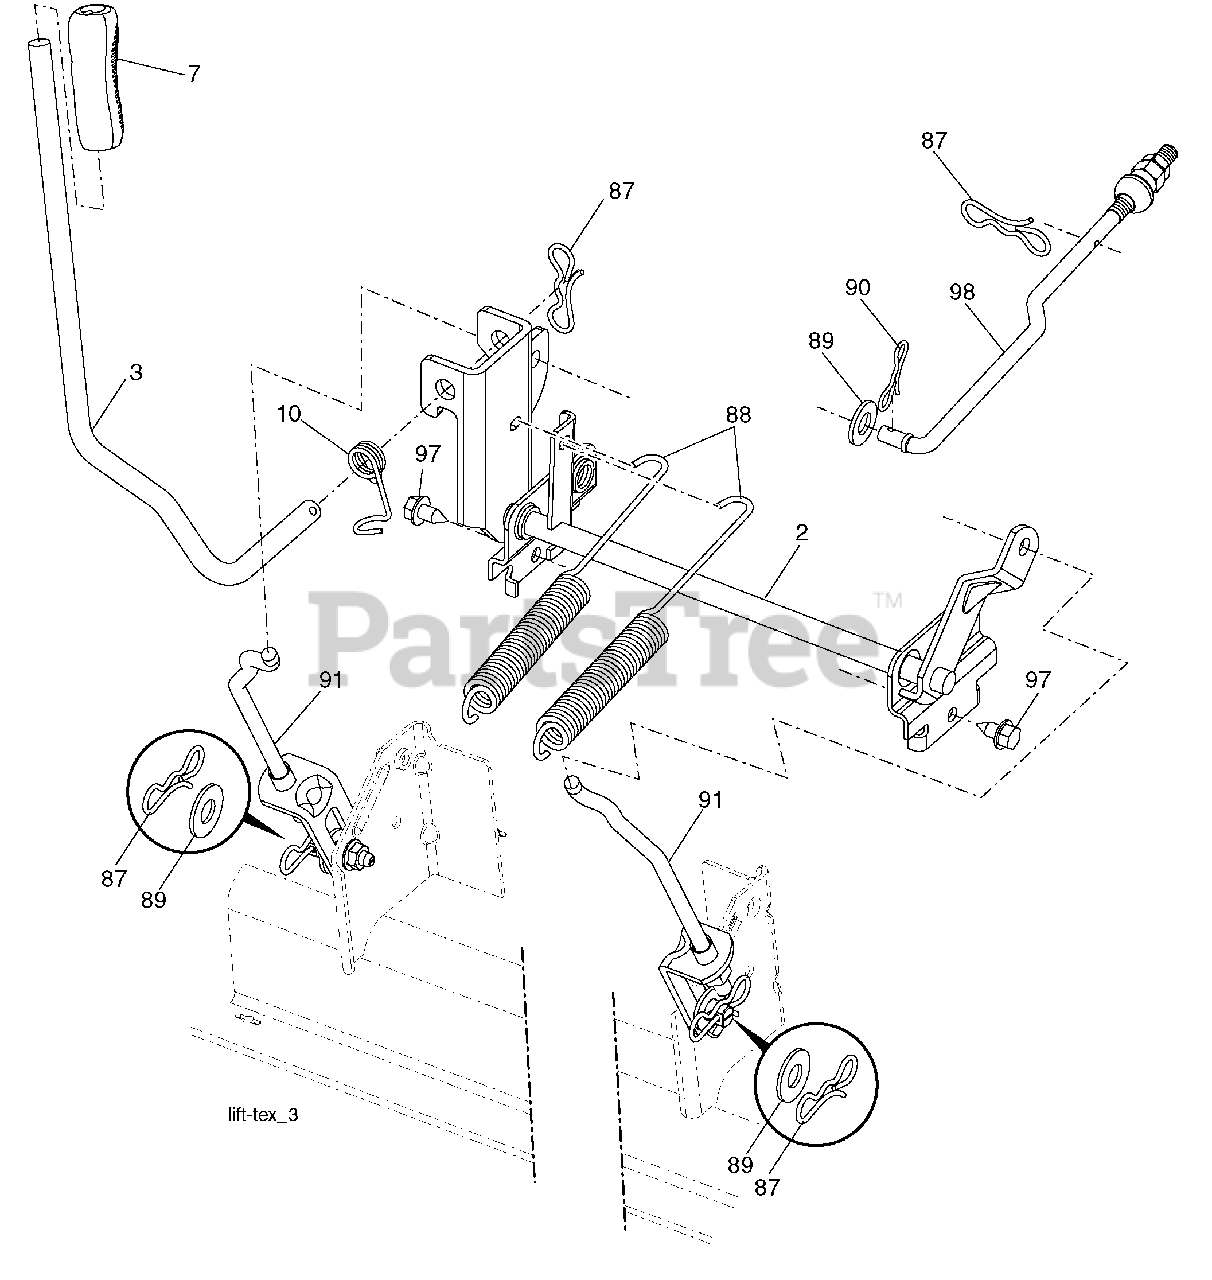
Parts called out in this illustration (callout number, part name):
2	Shaft Asm. Cross, Lift
3	Lever Asm., Lift
7	Grip, Lever
10	Spring Torsion
87	Pin Cotter 7/16 Bow Tie Lock
88	Spring Lift Assist
89	Washer Clear Zinc
90	Pin Cotter 5/16 Bow Tie Lock
91	Link Lift Susp Mower Rear
97	Screw 3/8-16 x .75
98	Link Lift Susp. Front Mower
